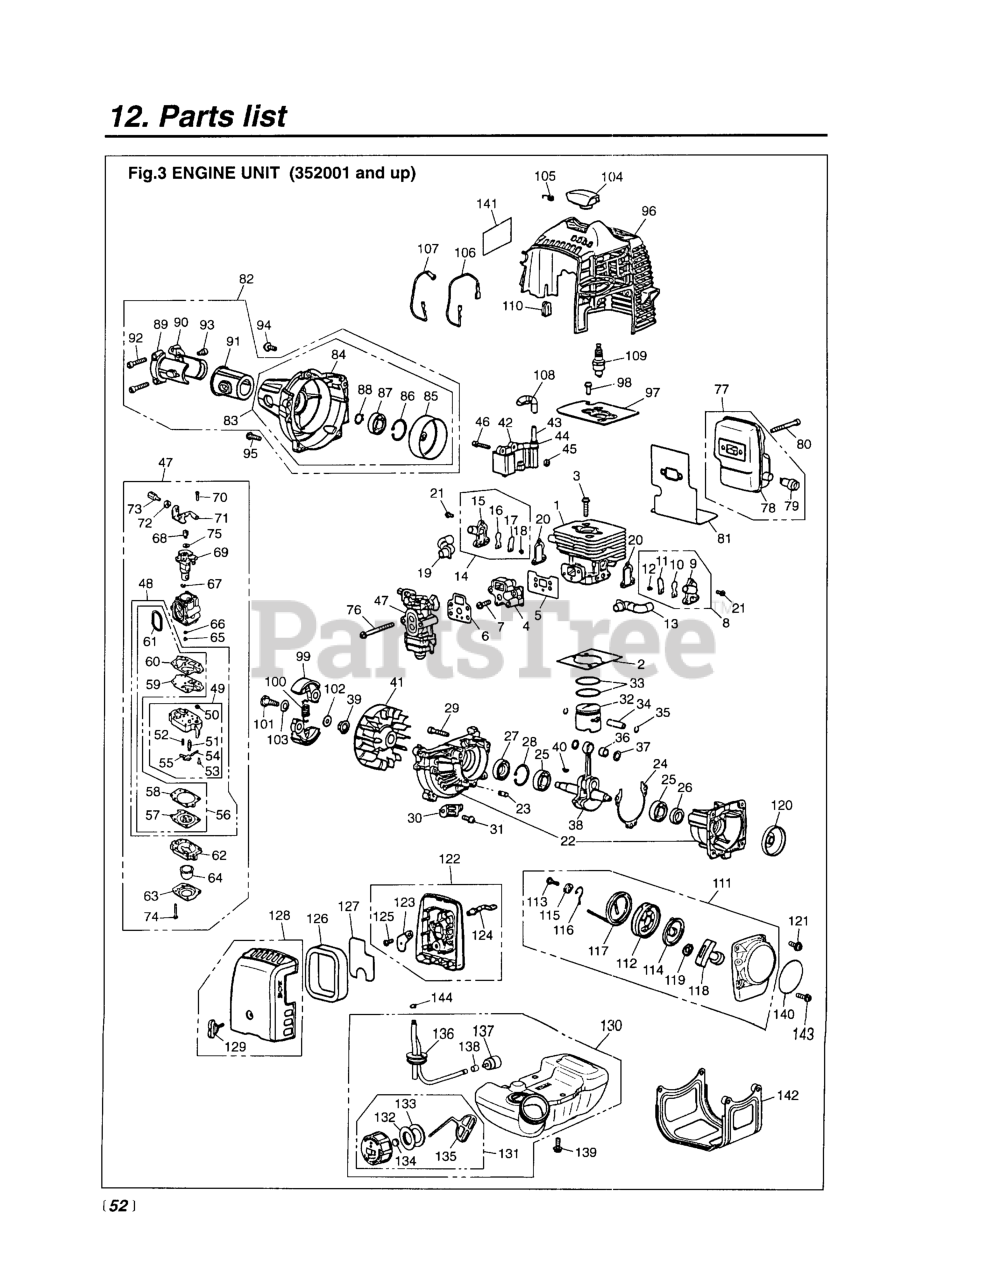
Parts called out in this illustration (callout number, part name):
1	CYLINDER (RPLS -12110)
2	GASKET, BASE
3	BOLT, M5 X 22
4	INSULATOR (RPLS. -13160/13161)
5	GASKET, INSULATOR
6	GASKET, CARBURETOR
7	SCREW, M5X20 (RPLS.1400-75510)
9	CASE VALVE
10	VALVE, REED
11	STOPPER
12	SCREW, M3 x 8
13	PIPE, AIR
16	VALVE, REED
17	STOPPER
18	SCREW, M3 x 8
19	PIPE, AIR (F)
20	GASKET, VALVE
21	SCREW
22	CRANKCASE-C
23	PIN
24	GASKET
25	BEARING
26	SEAL
27	SEAL, OIL (RPLS 1140-21220)
28	RING, SNAP, M28 x 1.2
29	BOLT, M5 X 30
32	PISTON
33	RING, PISTON
34	PIN
35	RING, SNAP (RPLS 1101-41320)
36	BEARING (RPLS 1140-41330)
37	WASHER
38	CRANKSHAFT COMPLETE
40	KEY
41	ROTOR
42	COIL-A
43	CORD
44	CAP
45	SPACER (RPLS -71260)
46	BOLT, M4 x 22
47	CARBURETOR (WYA-1-1)
48	REBUILD KIT
49	BODY-A
50	SCREEN
51	VALVE, INLET
53	SCREW
54	PIN
55	LEVER
56	KIT, GASKET (REPLACES-06020)
57	DIAPHRAGM
58	GASKET, DIAPHRAGM
59	DIAPHRAGM, PUMP
60	GASKET, PUMP
61	RING
62	BODY, PURGE
63	COVER, PUMP
64	PUMP, PRIMING
65	JET (REPLACES 4810-81250)
66	RING, O
67	RING
68	SWIVEL
69	VALVE ASSY
70	SCREW
72	NUT, CABLE ADJUSTER
73	SCREW, CABLE ADJUSTER
74	SCREW
75	WASHER
76	SCREW, M5 x 60
77	MUFFLER ASSEMBLY
78	MUFFLER (REPLACES -15110)
79	ARRESTER
80	BOLT, M5 x 50
81	GASKET (RPLS T1501-15210)
82	COVER-A (USE -31002)
83	COVER-C (USE -31102)
84	COVER, FAN (USE -31111)
86	RING, SNAP, M28 x 1.2
88	RING, SNAP (RPLS 3130-13270)
89	BRACKET (A) (RPLS -31210)
90	BRACKET (B) (REPLACES -31220)
91	CUSHION
92	BOLT, M5 X 30
93	BOLT (USE 3310-31720)
94	SCREW
95	SCREW, M5X20 (RPLS.1400-75510)
96	COVER, ENGINE (RPLS -32110)
97	PLATE, CYLINDER
98	SCREW, M5 X 10
99	SHOE
100	SPRING
101	BOLT
102	WASHER, FLAT (USE 182303)
103	WASHER (RPLS -51241)
104	CAP (RPLS 4810-72110)
105	SPRING
106	CORD (BLACK)
107	CORD, EARTH (RED)
108	TUBE
110	GROMMET
111	RECOIL ASSEMBLY
112	REEL
113	SCREW
114	SPRING, SPIRAL
115	COLLAR
116	ARM
117	ROPE (REPLACES 4500-75160)
118	KNOB (RPLS -75420)
119	PLATE, STOPPER
120	PULLEY
121	SCREW
122	BODY ASSEMBLY
123	PLATE, CHOKE
124	LEVER, CHOKE
125	SCREW (REPLACES 50030272)
126	ELEMENT
127	SCREEN
128	COVER ASSEMBLY
129	KNOB (RPLS -82220)
130	TANK ASSY (RPLS-85001)
131	CAP ASSY (RPLS -85201)
132	HOLDER (REPLACES -85230)
133	PACKING
134	FILTER
135	STOPPER
136	PIPE COMPLETE
137	FILTER ASSY
138	CLIP (REPLACES 2841-31280)
139	SCREW
140	LABEL, RECOIL
141	LABEL, COVER (RPLS -31130)
142	GUARD (RPLS 4810-31911)
143	SCREW, M5 x 25
144	CLIP
